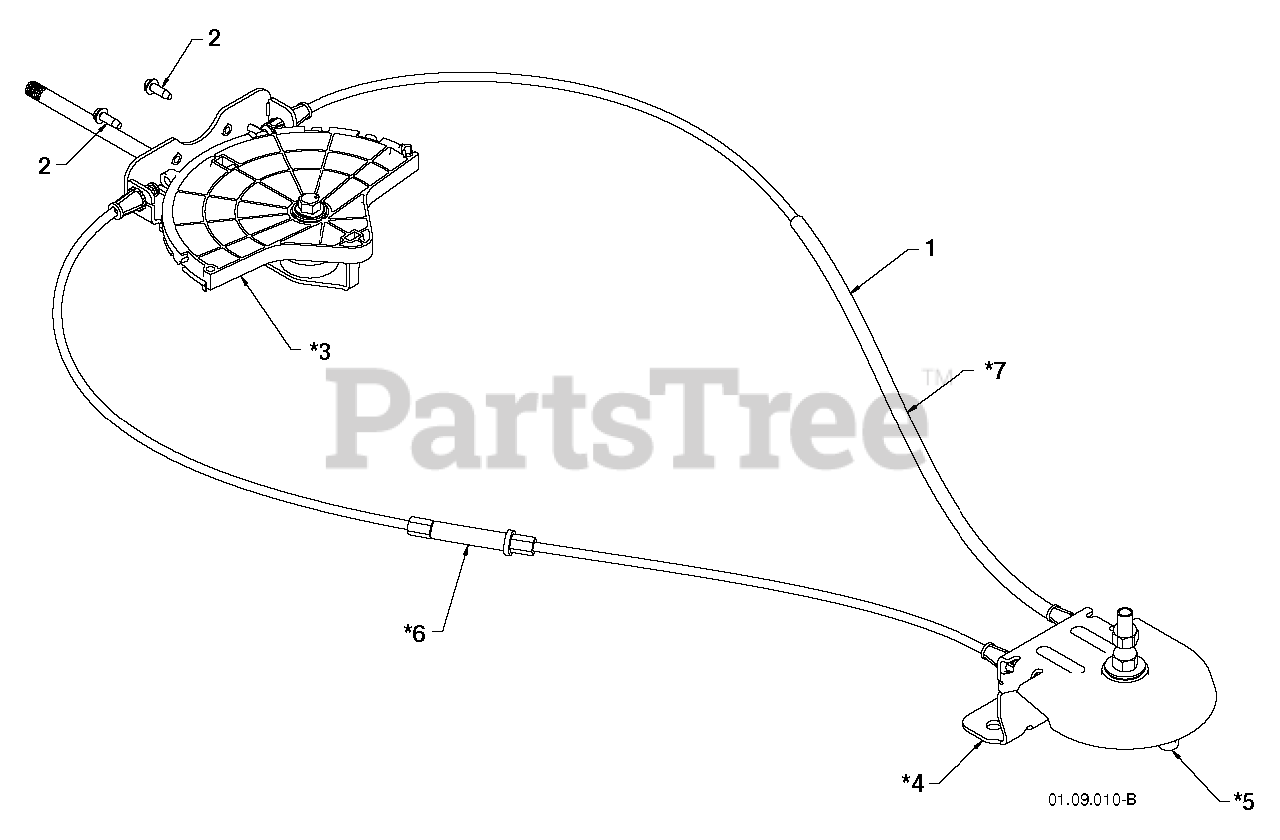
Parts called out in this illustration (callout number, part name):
1	LEVER/CABLE.ASM.ROTATOR
2	SCREW
3	CHUTE.ROT.HEAD.SERVICE
4	SNOW.PIVOT.BRKT.BLK.SERVICE
5	SNOW.PIVOT.PULLY
6	SNOW.CBL.ASM.ADJ.SERVICE(74)
7	SNOW.CBL.ASM.SERVICE(428272)
